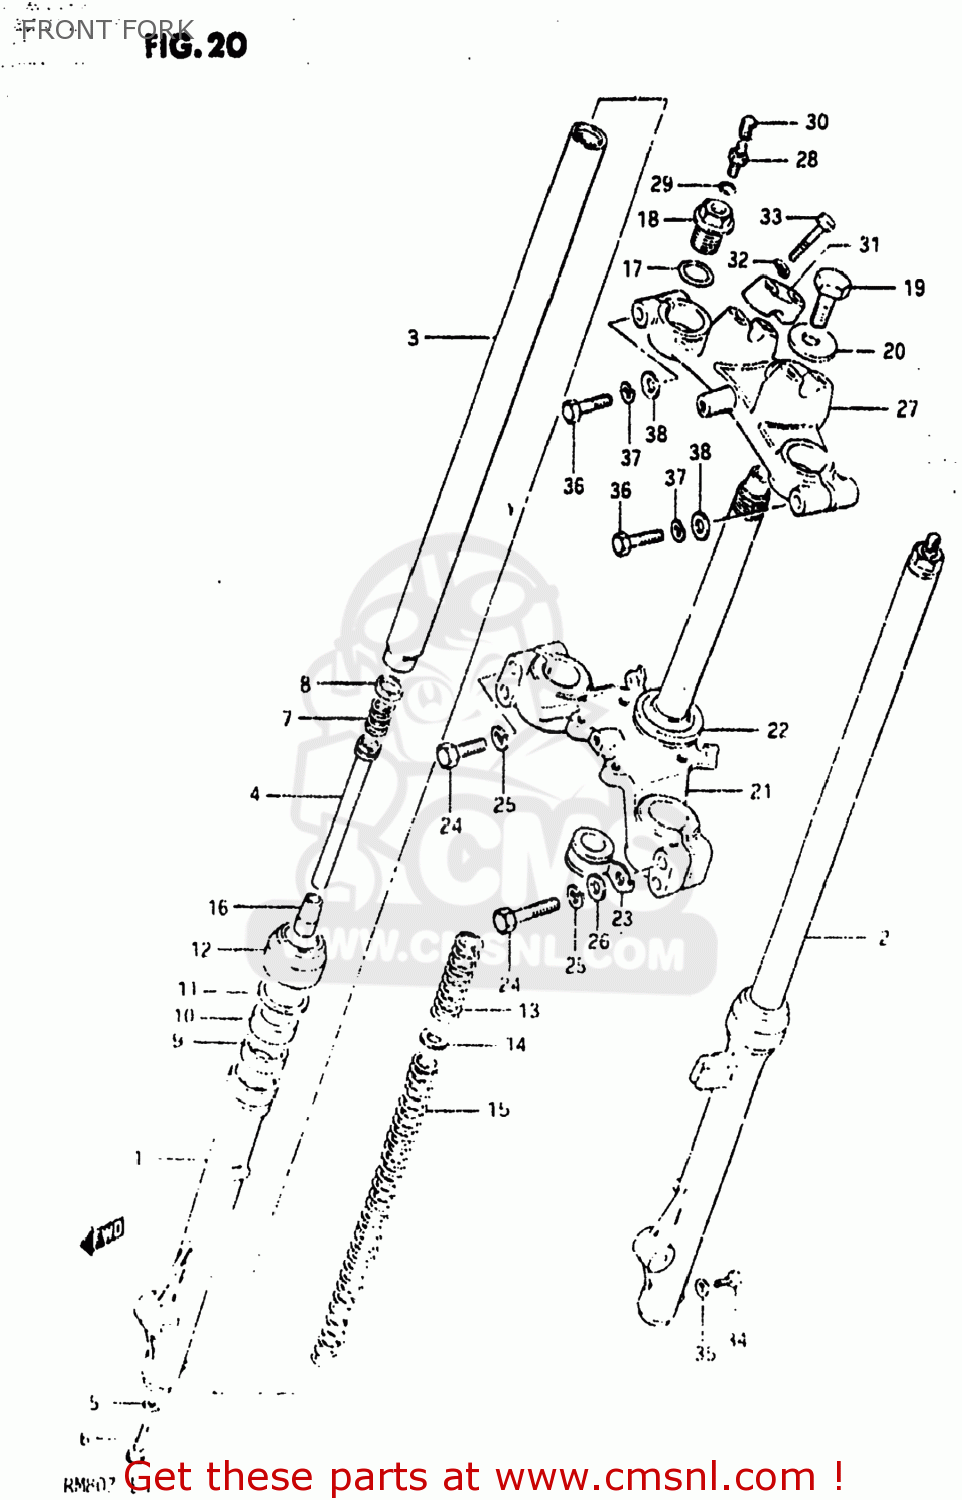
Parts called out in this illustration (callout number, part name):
1	TUBE,OUTER,RIGHT
2	TUBE,OUTER,LEFT
3	TUBE,FORK,INNER
4	CYLINDER,FRONT FORK
5	GASKET (NAS)
6	BOLT(8X27)
7	SPRING,REBOUND
8	RING,PISTON
9	SPACER,SEAL
10	SEAL,OIL
11	CIRCLIP,FORK OIL SEAL
12	SEAL,DUST
13	SPRING,FRONT FORK
14	SEAT,SPRING
15	SPRING,FRONT FORK
16	PIECE,OIL LOCK
17	O RING
18	BOLT,FORK INNER TUBE
19	BOLT,STEERING STEM HEAD
20	WASHER
21	STEM,STEERING
22	RACE,STEERING OUTER LWR
23	GUIDE,CABLE
24	BOLT,M10X1.25X
25	LOCK WASHER
26	WASHER
27	HEAD,STEERING STEM
28	VALVE,FRONT FORK AIR
29	O-RING
30	CAP
31	HOLDER,HANDLEBAR
32	LOCK WASHER
33	BOLT
34	BOLT
35	GASKET,DRAIN,PLUG (NAS)
36	BOLT 8X40
37	LOCK WASHER
38	WASHER
